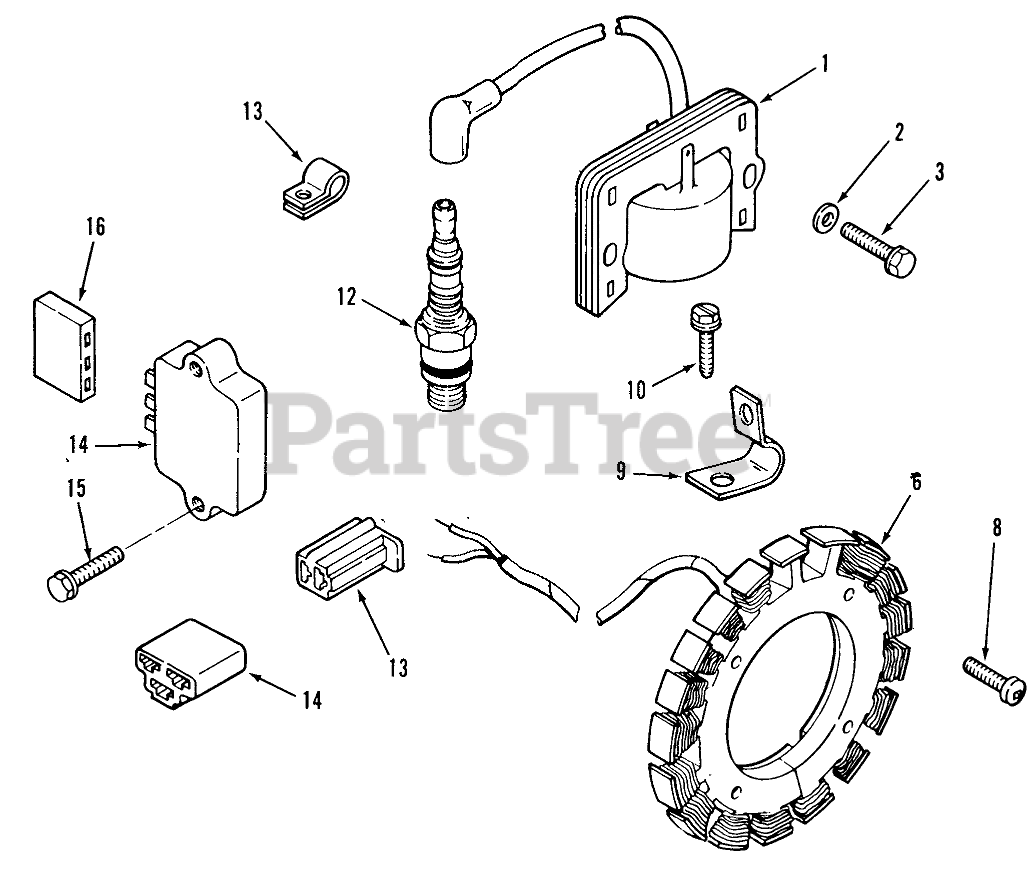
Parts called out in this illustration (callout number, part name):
1	Ignition Module (Before Serial No. 1715900013)
2	Washer
3	Screw
6	Stator Kit 15 amp (Includes Item # 8)
8	Screw
9	Clip
10	Hex. Washer Hd. Screw No. 8-32 x 3/8
12	Plug-Spark
13	Clip-Cable
14	Regulator-Rectifier
15	Screw
16	Connector
